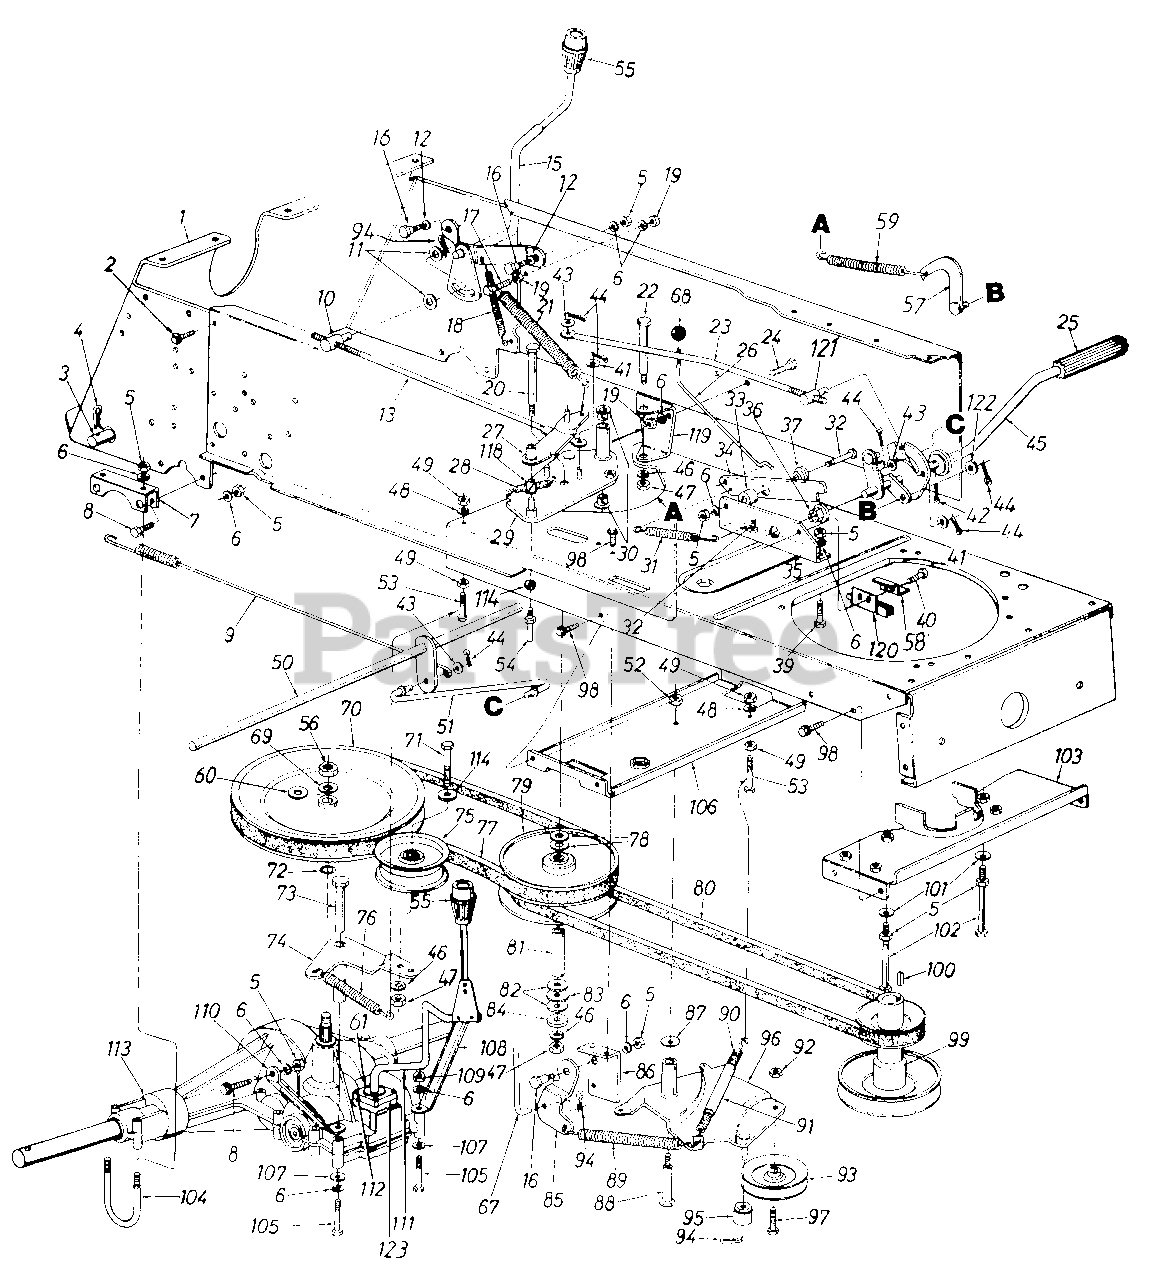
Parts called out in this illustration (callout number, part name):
3	Hitch Rod
4	Hitch Pin Clip
5	Hex Nut 5/16-18 Thd.
6	L-Wash. 5/16" I.D.
7	Transaxle Bracket
8	Hex Bolt 5/16-18 x .75" Lg. (Gr. 5)
9	Brake Extension Spring
10	Adjustment Ferrule 3/8-24 Thd.
11	Fl-Wash. .385" I.D. x .87"
12	Spr. Wash. .445" I.D. x .75" O.D.
13	Speed Control Link (Rear)
15	Speed Selector Lever Ass'y.
16	Shld. Bolt .437" Dia. x .162"
17	Hex Bolt 5/16-24 x 1.25" Lg.
18	Extension Spring 3.9" Lg.
19	Hex Nut 5/16-24 Thd. (Gr. 5)
20	Hex Bolt 3/8-24 x 4.5" Lg.
21	Extension Spring 11" Lg.
22	Shld. Bolt .625" Dia. x 3.5" Lg.
23	Speed Control Link (Front)
24	Hex Bolt 5/16-24 x .75" Lg.
25	Foot Pad
26	Parking Brake Link
29	Pulley Plate Ass'y.
30	Flanged Brg. .630" I.D.
31	Extension Spring 2.51" Lg.
32	Hex Bolt 5/16-18 x 1.25" Lg.
33	Spacer .34" I.D. x .88"
36	Hex Flange Brg. .634" I.D.
37	Shld. Spacer .5" Dia.
39	Hex Bolt 5/16-18 x .75" Lg.
40	Hex B-Tap Scr. #10 x 5/8 Lg.
41	Fl-Wash. .406" I.D. x .75" O.D.
42	Cotter Pin 1/8" Dia.
43	Fl-Wash. .34" I.D. x .68" O.D.
44	Cotter Pin 3/32" Dia.
47	Hex Nut 3/8-24 Thd.
48	L-Wash. 1/4" I.D.
49	Hex Nut 1/4-20 Thd.
50	Brake Link Bracket
51	Front Brake Rod Link
52	Hex Cent. L-Nut 3/8-16 Thd.
53	Hex Bolt 1/4-20 x .20" Lg.
54	Belt Guard Pin
55	Shift Knob
56	Hex Jam Nut 9/16-18 Thd.
57	Foot Pedal Brkt. Ass'y.
58	Switch Plate
59	Ext. Spring 5.2" Lg.
60	Fl-Wash. .635" I.D. x 1.12" O.D.
61	Shift Snout
67	Deck Control Rod
68	Ball Knob Brake
69	Bell-Wash. 9/16" I.D. x 1.25"
70	V-Pulley 9-1/4" O.D.
71	Hex Bolt 3/8-24 x 1.75" Lg.
72	Wire Ring
73	Shld. Bolt 5/16-24 Thd.
74	Idler Brkt. Ass'y.
75	Flat Idler 3.5" O.D.
76	Extension Spring 6.12" Lg.
77	V-Belt
78	Teflon Washer 1.20" O.D.
79	Variable Speed Pulley 6" Dia.
80	V-Belt
81	Pivot Bushing
82	Fl-Wash. .56" I.D. x 1.0" O.D.
83	Thrust Brg. .56" I.D. x 1.25"
84	Retainer Cup
85	Deck Control Pivot Brkt.
86	Parking Brake Mtg. Brkt.
87	Bell-Wash. .38" I.D. x .88" O.D.
88	Shld. Bolt .498" Dia. x 2.05"
89	Extension Spring 6.12" Lg.
90	Extension Spring 6.37" Lg.
91	Convoluted Conduit 4" Lg.
92	Hex Cent. L-Nut 3/8-24 Thd.
93	V-Belt Idler
94	Internal Cotter Pin
95	Spacer
96	Idler Brkt. Deck Ass'y.
97	Hex Bolt 3/8-24 x 1.5" Lg.
98	Hex TT-TAp Scr. 1/4-20 x .5"
99	Engine Pulley
100	Sq. Key 1/4 x 1.5" Lg.
101	Bell-Wash. .345" I.D. x .88"
102	Hex Bolt 5/16-18 x 5.25" Lg.
105	Hex Bolt 5/16-24 x 2.25" Lg.
107	Fl-Wash. .344" I.D. x .62" O.D.
108	Front Trans. Support Brkt. - L.H.
109	Hex Nut 5/16-24 Thd.
110	Front Trans. Support Brkt. - R.H.
111	Shift Lever Ass'y. Complete
112	Hex Flange Bolt 1/4-20 Thd.
113	2-Speed Transmission Comp.
114	Fl-Wash. 3/8" I.D. x 1.0" O.D.
118	Nyliner Flanged Brg.
119	Variable Speed Support Brkt.
120	Safety Switch (Clutch)
121	Adjustment Ferrule 3/8-24 Thd.
122	Fl-Wash. .344" I.D. x .62" O.D.
